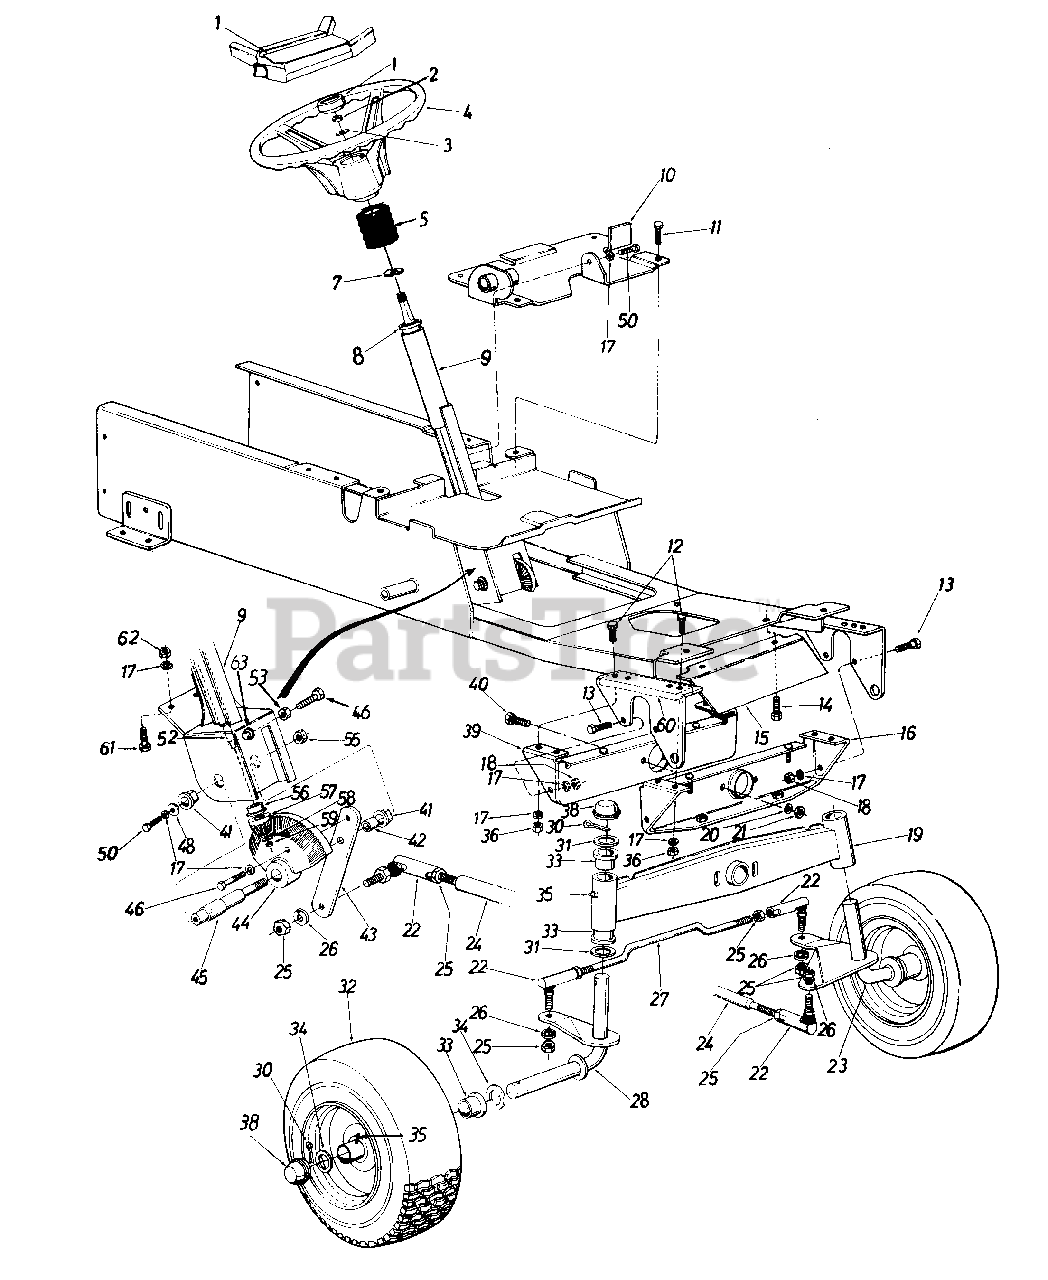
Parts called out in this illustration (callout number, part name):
1	Steering Wheel Cap
2	Hex Cent. L-Nut 5/16-24 Thd.
3	Bell-Wash. 5/16" I.D.
4	Steering Wheel
5	Steering Bellow
7	Wave Wash. .660" I.D. x .88" O.D.
8	Ball Brg. .63" I.D. x 1.38" O.D.
10	Dash Panel Base Plate Ass'y.
11	Hex Self-Tap Scr. 3/8-16 x .75" Lg.
12	Hex Bolt 3/8-16 x 1.50" Lg.
13	Hex Bolt 3/8-16 x 1.00" Lg.
14	Hex Wash. S.F. Tap Scr. 3/8-16 x 1.25" Lg.
15	Dust Shield
18	Hex Nut 3/8-16 Thd.
19	Pivot bar Ass'y.
20	Bell-Wash. 3/8" I.D.
21	Hex Cent. L-Nut 3/8-16 Thd.
22	Drag Link End
23	Axle Ass'y.-L.H.
24	Drag Link
25	Hex Nut 1/2-20 Thd.
26	L-Wash. 1/2" I.D.
27	Tie Rod
28	Axle Ass'y.-R.H.
30	Cotter Pin 3/16" Dia. x 1.50" Lg.
31	Fl-Wash. 1.00" I.D. x 1.62" O.D.
33	Flange Brg. 1" I.D.
34	Fl-Wash. 1" I.D. x 1.25" O.D.
35	Grease Fitting
36	Hex Nut 3/8-16 Thd.
38	Dust Cover
41	Flange Brg. w/Flats .753" I.D.
42	Steering Gear Shaft Spacer
43	Steering Arm
44	Bevel Gear
45	Steering Gear Shaft
46	Hex Bolt 3/8-16 x 1.50" Lg.
48	Fl-Wash. .406" I.D. x 1.25" O.D.
50	Hex Bolt 3/8-16 x .75" Lg.
52	Steering Shaft
53	Hex Jam Nut 3/8-16 Thd.
55	Hex Ins. L-Nut 1/2-20 Thd.
56	Hex Flange Brg. .630 I.D.
57	Pinion Gear
58	Fl-Wash. 3/8" Dia.
59	Hex Cent. L-Nut 5/16-24 Thd.
62	Hex Nut 3/8-24 Thd.
